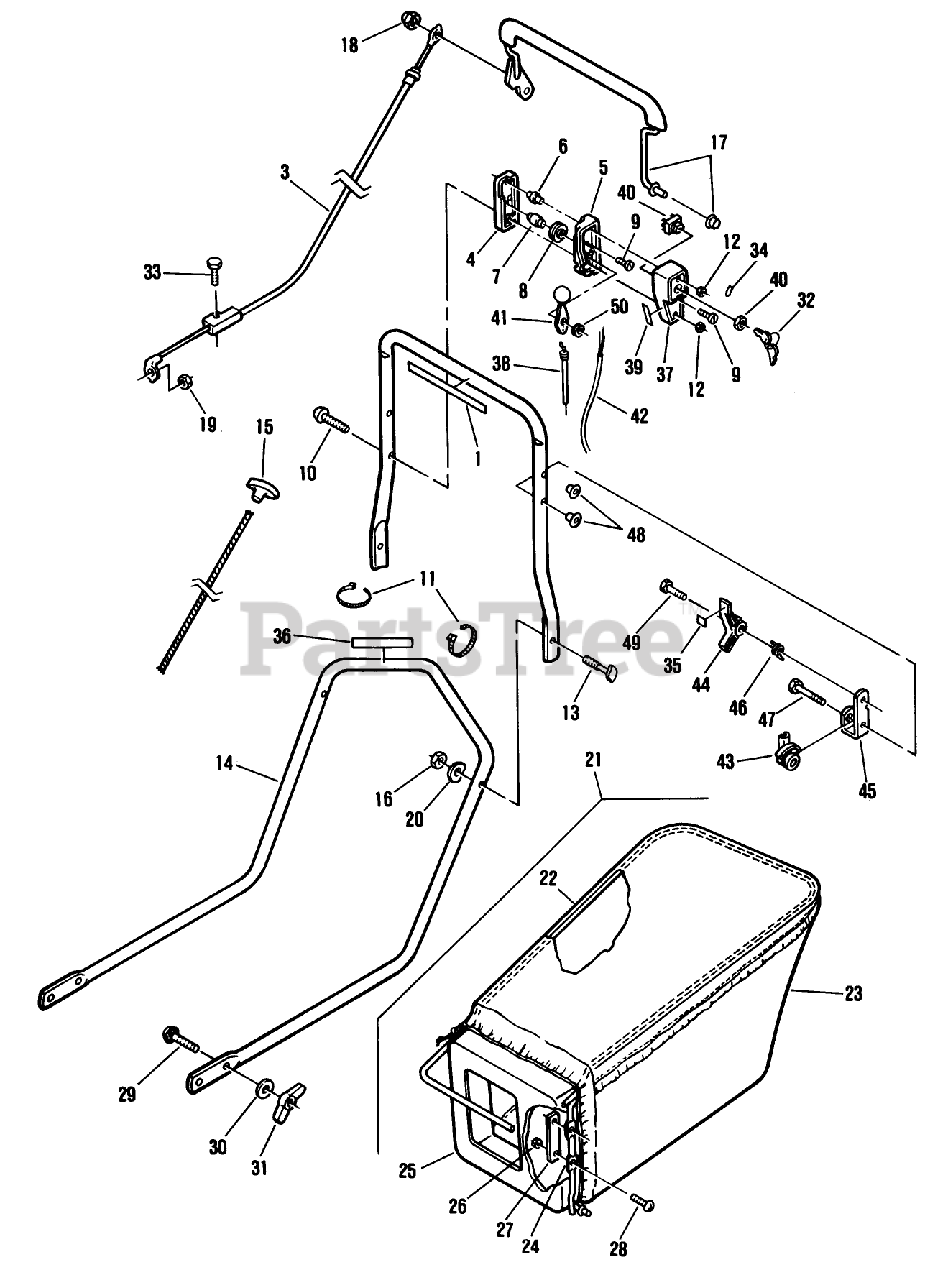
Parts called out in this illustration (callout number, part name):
3	CONTROL CABLE WES
6	COLUMN
7	PIN SKF
8	PULLEY PL
9	SCREW
10	SCREW
12	NUT C/LOCK E
15	HANDLE START UM&D
16	NUT-LOCK F
18	NUT ACORN
19	LOCKNUT E
20	WASHER-CURVED
22	HANGER BAG TROX
25	BAG ADAPTOR PL
26	LOCKNUT E
30	WASHER
31	NUT-WING
33	SCREW-HH
40	SWITCH AY
41	LEVER&KNOB AY WES
47	BOLT QUALITY
50	WASHER-SPRING
